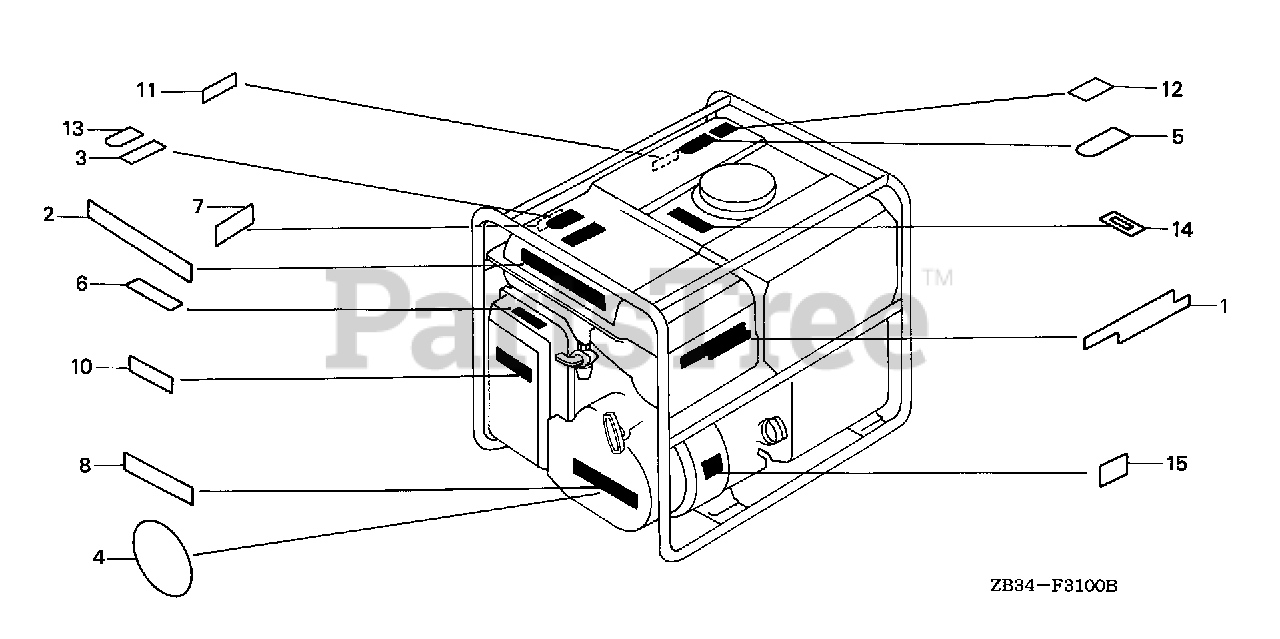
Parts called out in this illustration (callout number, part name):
1	EMBLEM (EB2500)
2	PLATE, CAUTION
3	LABEL, RAIN WARNING (ENGLISH)
5	MARK, CAUTION (ENGLISH/FRENCH/SPANISH)
6	MARK, CHOKE
10	MARK, AIR CLEANER (ENGLISH)
11	MARK, EX. CAUTION
12	MARK, CAUTION (ENGLISH/FRENCH/SPANISH)
13	LABEL, CONNECT WARNING (ENGLISH)
14	PLATE, FUEL INDICATION
15	MARK, OIL CAUTION
